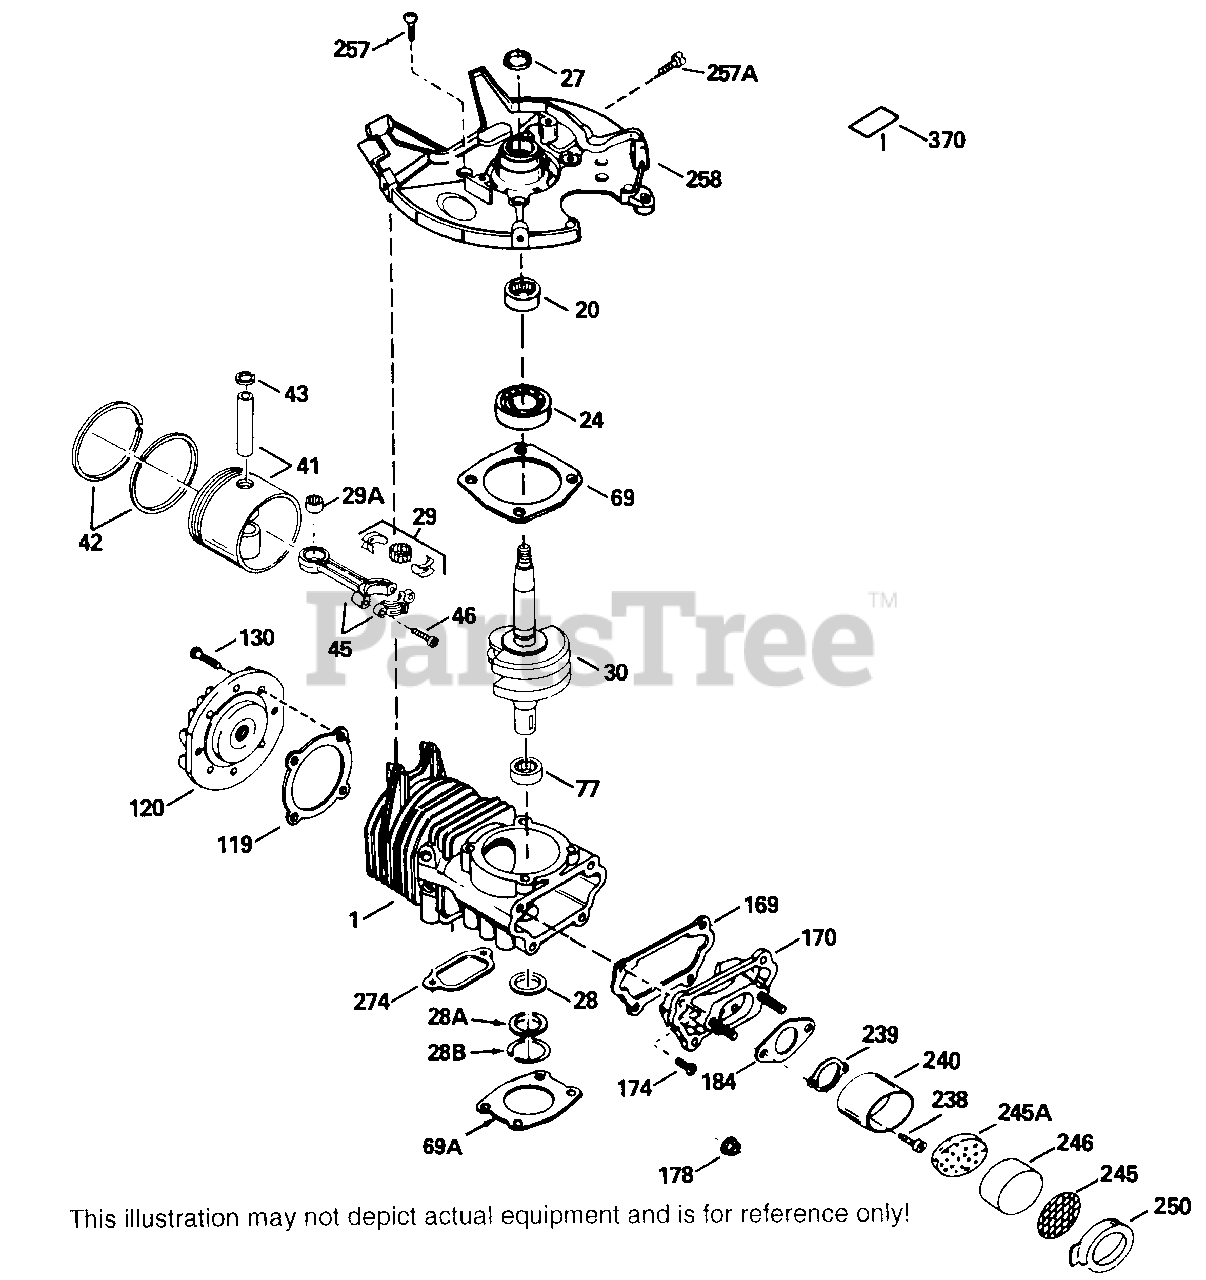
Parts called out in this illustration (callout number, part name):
1	"Cylinder
24	Bearing, Ball
27	Seal, Crankshaft
28	Seal, Crankshaft
28A	Retainer, Crankshaft seal
28B	Ring, Crankshaft seal retainer
29	Bearing & Liner Set, Needle 37 needle s
29A	Bearing, Needle
30	Crankshaft
41	Piston & Pin Assy.
42	Ring Set, Piston
43	Ring, Piston pin retaining
45	Rod Assy., Connecting Incl. 29, 29A& 46
46	Screw, Connecting rod
69	Gasket, Housing base
77	Bearing, Needle
119	Gasket, Cylinder head
120	Cylinder Head
130	Screw, 1/4-20 x 3/4"
169	Gasket, Cover plate
170	Plate Assy., Reed & Cover
174	Screw, Torx T-25, 10-24 x 1/2"
178	Nut, Flange whiz-lock, 1/4-28
184	Gasket, Carburetor
238	Screw, Torx T-25, 10-32 x 5/8"
239	Gasket, Air filter
240	Body, Air filter
245	Air Filter
245A	Air Filter
246	Air Filter
250	Cover, Air filter
257	Screw, Torx T-30, 1/4-20 x 5/8"
258	Blower Housing Base
274	Gasket, Exhaust
370	Decal, Warning
